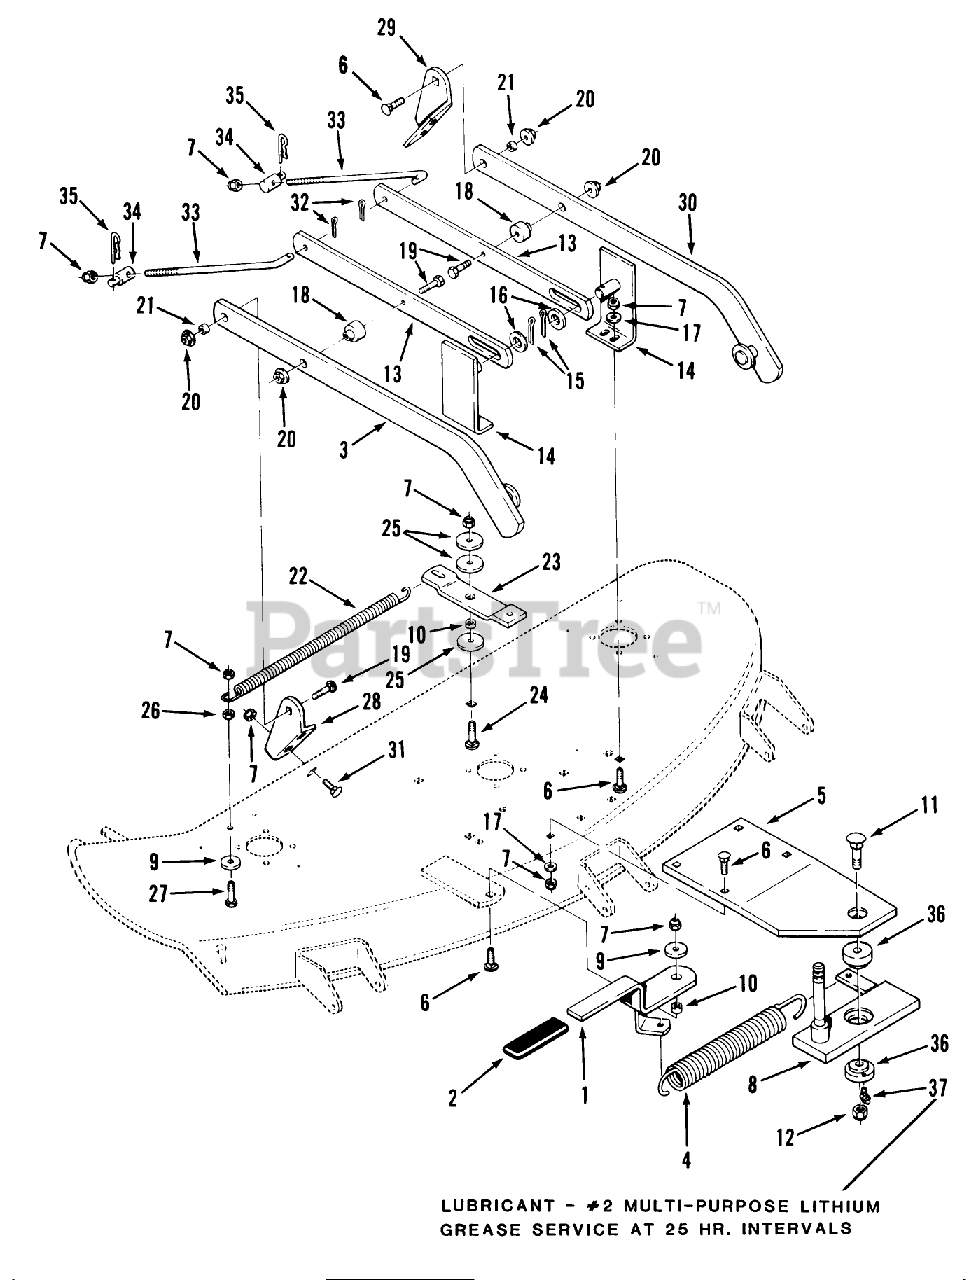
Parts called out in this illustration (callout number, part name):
9	WASHER
10	SPACER
13	BAR-LEVELER *R
18	SPACER
21	SPACER
22	SPRING-EXTENSION
34	TRUNNION-LIFT
35	Hairpin
36	BUSHING
